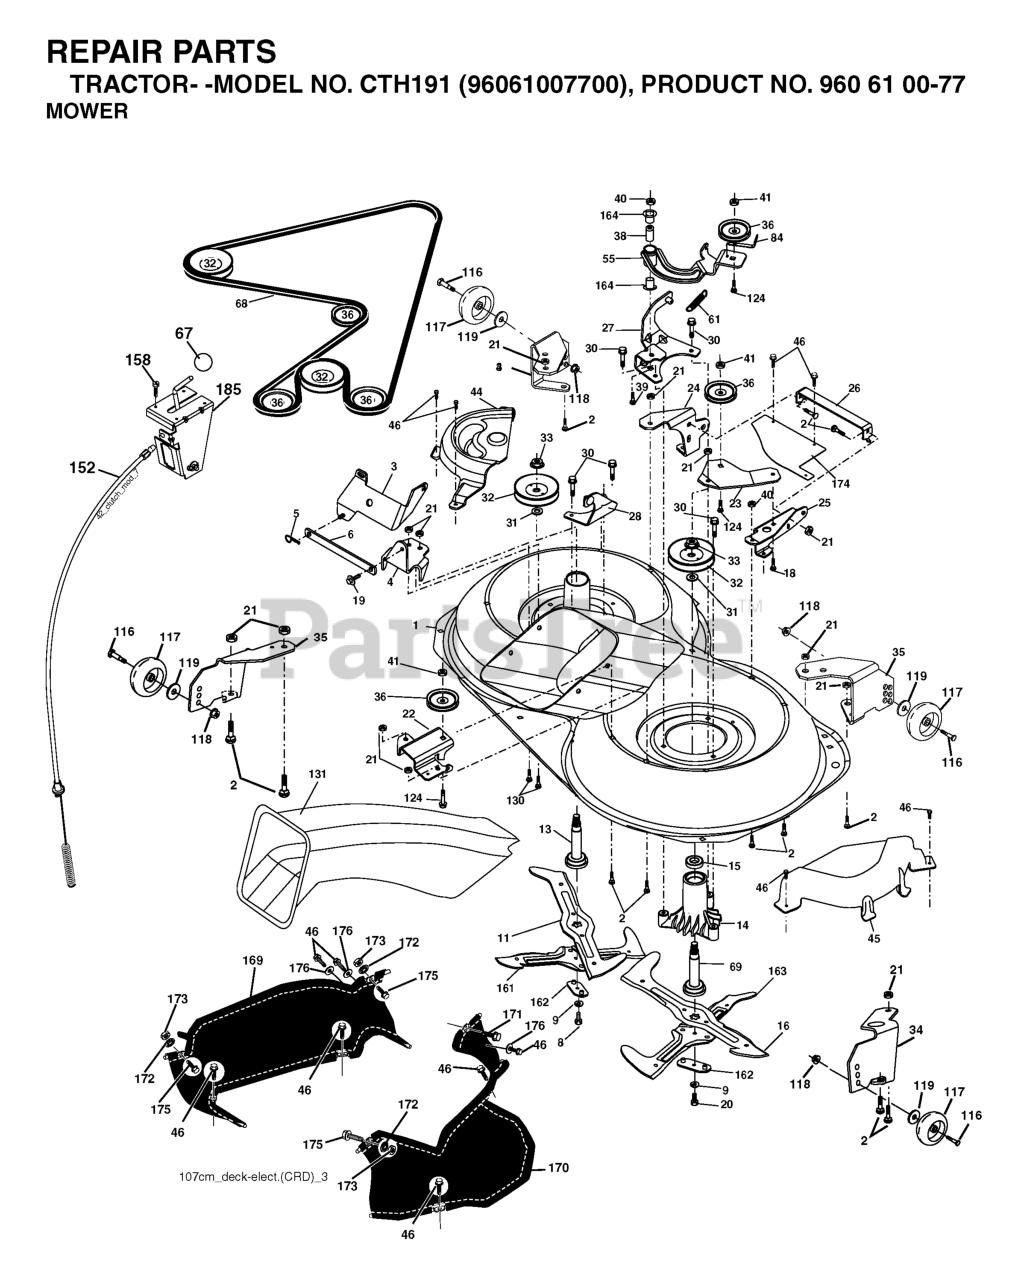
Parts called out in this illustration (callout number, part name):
1	Housing Asm. Mower 107 CRD
2	RP BOLT 5/16-18 X3/4 ZN/YEL GR
5	RETAINER-SPRNG RB
6	BAR.SWAY.92.CRD
8	BOLT.3/8-24X1.25 GR8
9	LOCKWASHER
11	BLADE.3N1.LH.CRD
13	SHAFT ASM VENT
14	HOUSING.MANDREL.VENTED (MACHD)
16	BLADE.3N1.RH.CRD
19	BOLT SHD 5/16-18
20	BOLT.3/8-24X1.25GR8. LHTHRD
21	LOCKNUT
22	BRACKET.IDLER.RR.107.CRD
25	BRACKET RF
26	SUPPORT
28	BRACKET
30	SCREW, WASHER HEAD
31	WASHER.SPACER.MANDREL
32	PULLEY.MANDREL.4.80 PD.2006
33	NUT.FLANGE.LOCK.TOP
34	BRACKET
35	BRACKET
36	PULLEY.IDLER.4.25
41	NUT LOCK FLG 3/8-16 UNC
45	COVER.MANDREL.RH.CRD
46	SCREW.1/4-20X5/8
55	ARM.IDLER.107.CRD
61	SPRING
67	KNOB T (3/8 HOLE)
68	HEX-BELT 107 MOWER
69	SHAFT.ASM.W/LWR.BRG.RH.THREAD
84	KEEPER, BELT IDLER
116	SHOULDER BOLT
117	RP WHEEL. GUAGE RALLY
118	LOCKNUT
119	WASHER.5/16.FLAT.STE.STD.
124	BOLT.3/8-16X1.50
130	BOLT.CARR.SQNK.5/16-18UNC.X3/4
131	CHUTE BAGGER
158	SCREW
163	BLADE.CROSS.RH.CRD.107
164	BRNG T
172	PUSH.NUT.ROUND.3/8.DIAM
173	NUT
174	PLATE
175	BOLT D
185	HEAD ASM. CABLE CLUTCH
